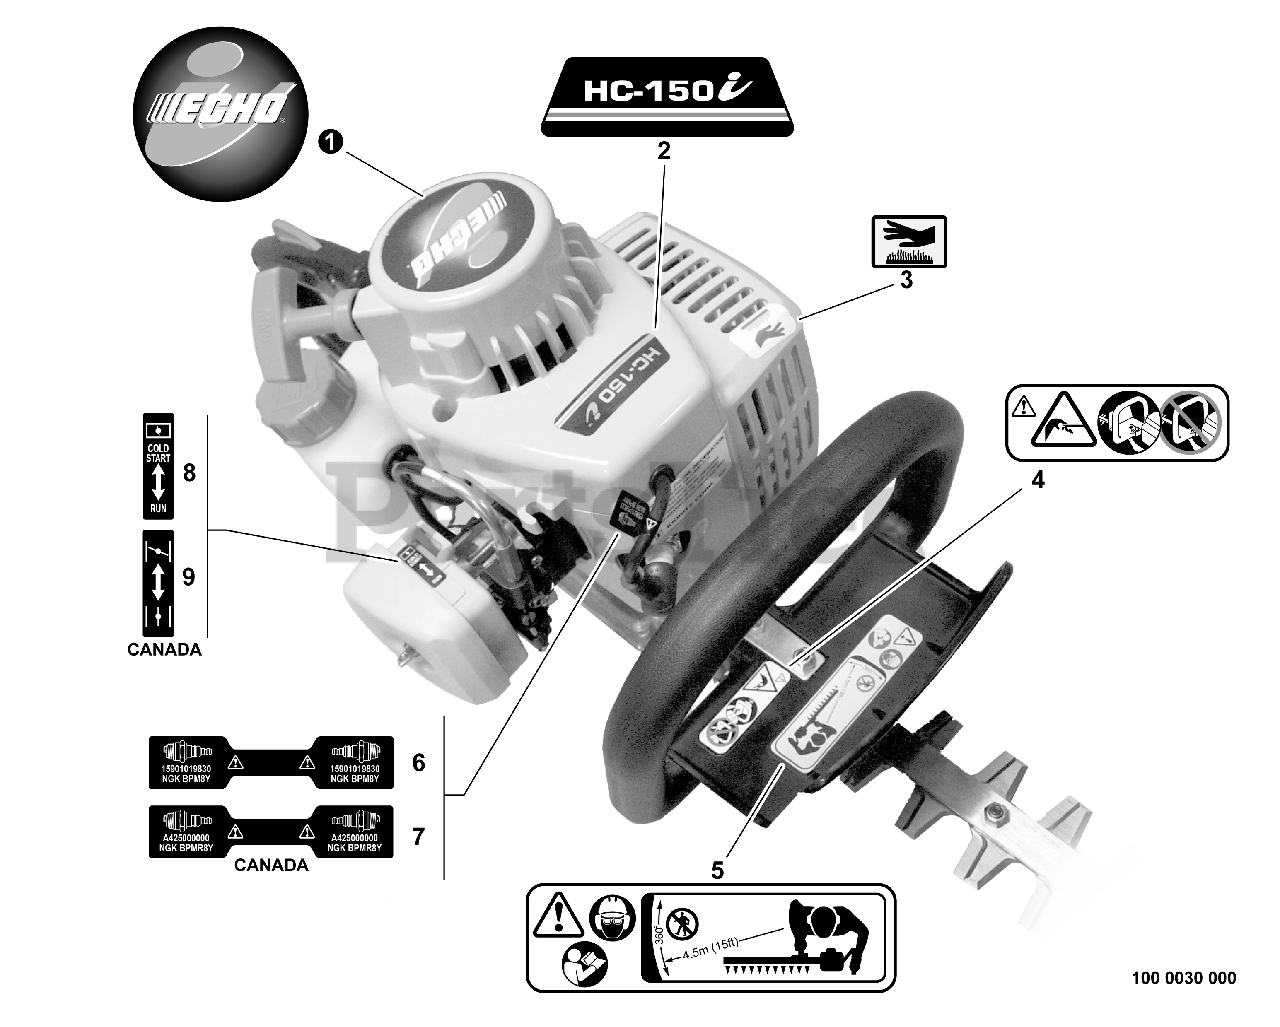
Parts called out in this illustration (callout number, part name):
1	LABEL - ECHO -- i
2	LABEL - MODEL HC-150i
3	LABEL - HOT SURFACE
4	LABEL - CAUTION
5	LABEL - CAUTION
6	LABEL - SPARK PLUG -- BPM-8Y
7	LABEL - SPARK PLUG -- BPMR-8Y
8	LABEL - CHOKE
9	LABEL - CHOKE
